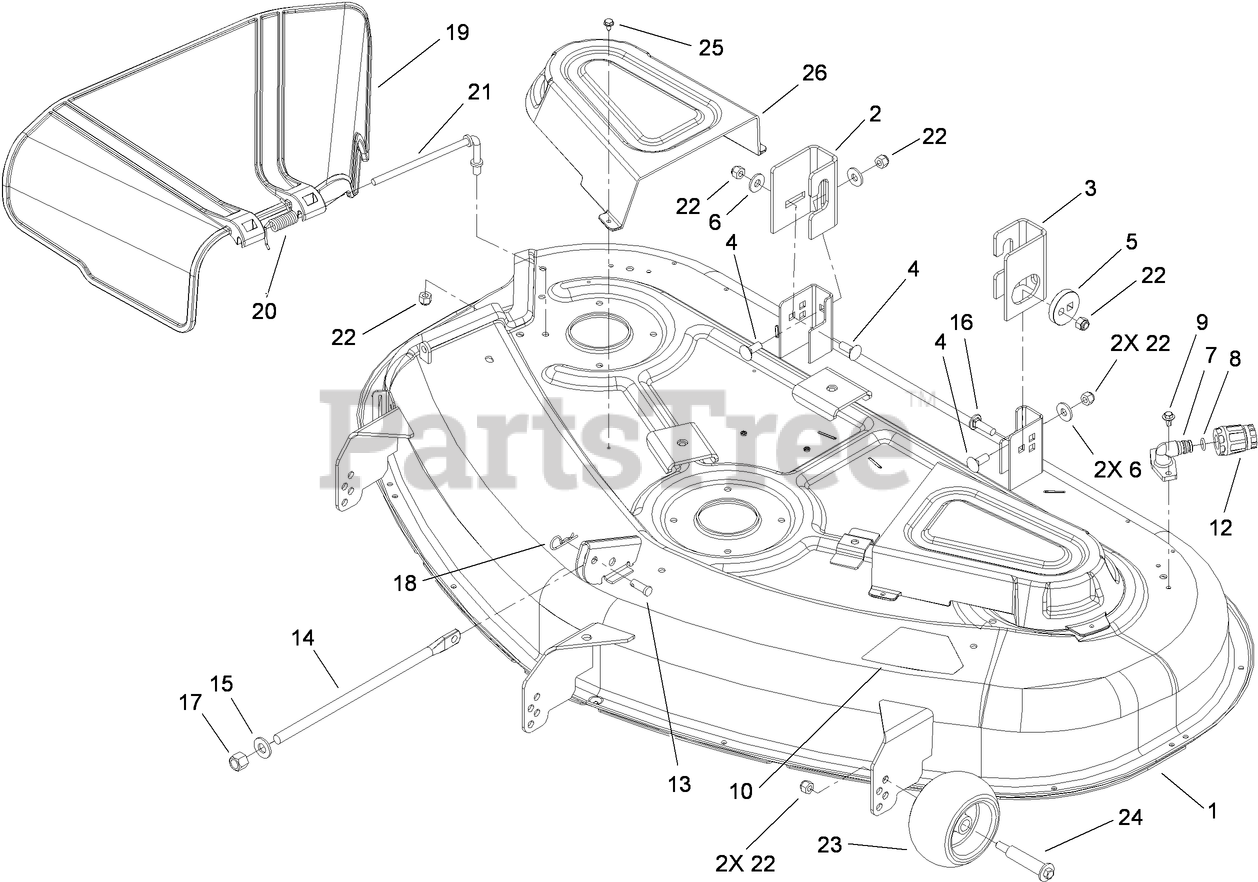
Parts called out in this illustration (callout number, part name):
2	BRACKET-HANGER, RIGHT REAR
3	BRACKET-HANGER, LEFT REAR
4	BOLT-CARR
5	ECCENTRIC
6	WASHER-HARDENED
8	O-RING
9	SCREW-HHFTF
12	CONNECTOR-HOSE
13	PIN-CLEVIS
14	ROD-LIFT
15	WASHER-THRUST
16	SCREW-CARR
17	NUT-LOCK, NI
18	PIN-HAIR
19	DEFLECTOR
20	SPRING-TORSION
21	ROD-PIVOT
22	NUT-LOCK, NI
23	ROLLER-SCALP, ANTI
24	BOLT-SHOULDER
25	SCREW-HWHTF
26	COVER-BELT
